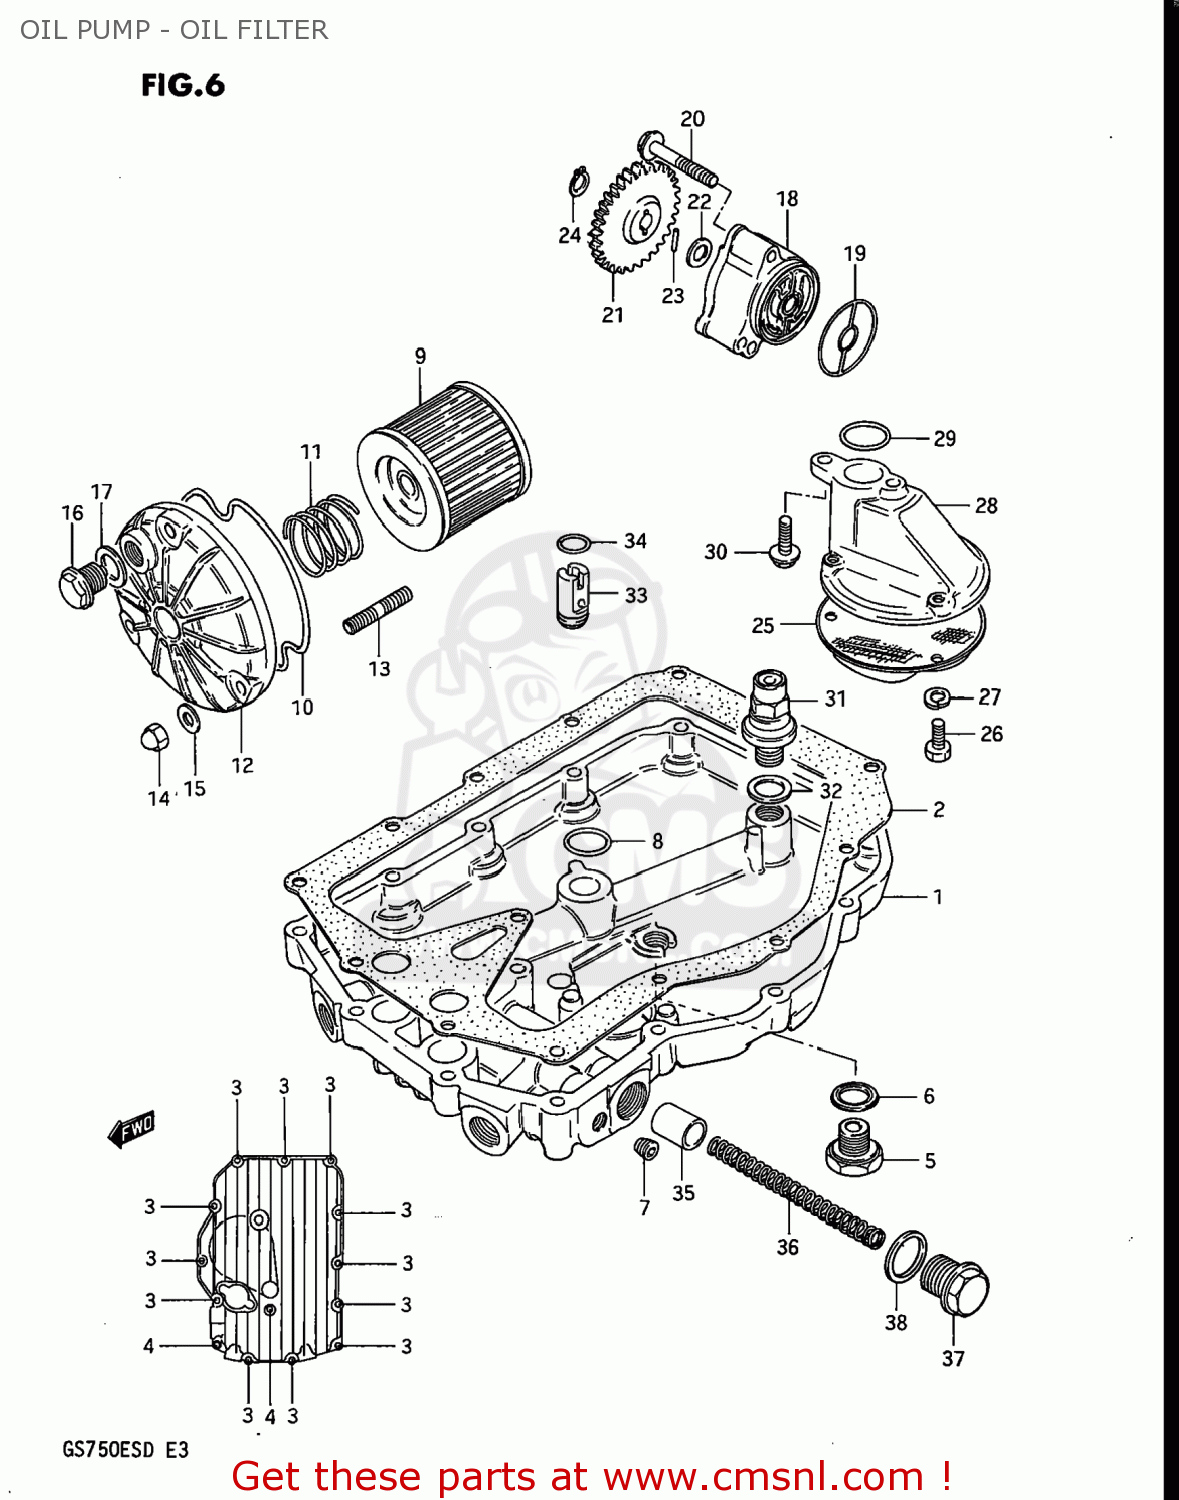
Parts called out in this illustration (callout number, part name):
1	PAN,OIL
2	GASKET,OIL PAN (MCA)
3	BOLT 6X30
4	BOLT (6X40)
5	PLUG
6	GASKET(14X19.2X2) (NAS)
7	PLUG
8	O RING(D:3.2,ID:15.8)
9	FILTER ASSY,ENGINE OIL
10	O RING,OIL FILTER CHAMBER CAP
11	SPRING
12	CAP,OIL FILTER
13	STUD 6X20
14	NUT 6MM
15	WASHER
16	PLUG (14X12)
17	GASKET(14X19.2X2) (NAS)
18	PUMP ASSEMBLY,OIL
19	O-RING,OIL PUMP
20	BOLT
21	GEAR,OIL PUMP DRIVEN
22	SHIM
23	PIN(4X15.8)
24	CIRCLIP
25	STRAINER,ENGINE OIL
26	BOLT
27	LOCK WASHER
28	PROTECTOR,OIL STRAINER
29	O RING(D:3.2,ID:17.8)
30	BOLT,REAR
31	REGULATOR ASSY,ENGINE OIL
32	WASHER
33	VALVE ASSEMBLY,PISTON OIL
34	O RING(D:1.3,ID:9.8)
35	PLUNGER,CONTROL
36	SPRING
37	PLUG
38	O RING(D:2.4,ID:16.8)
